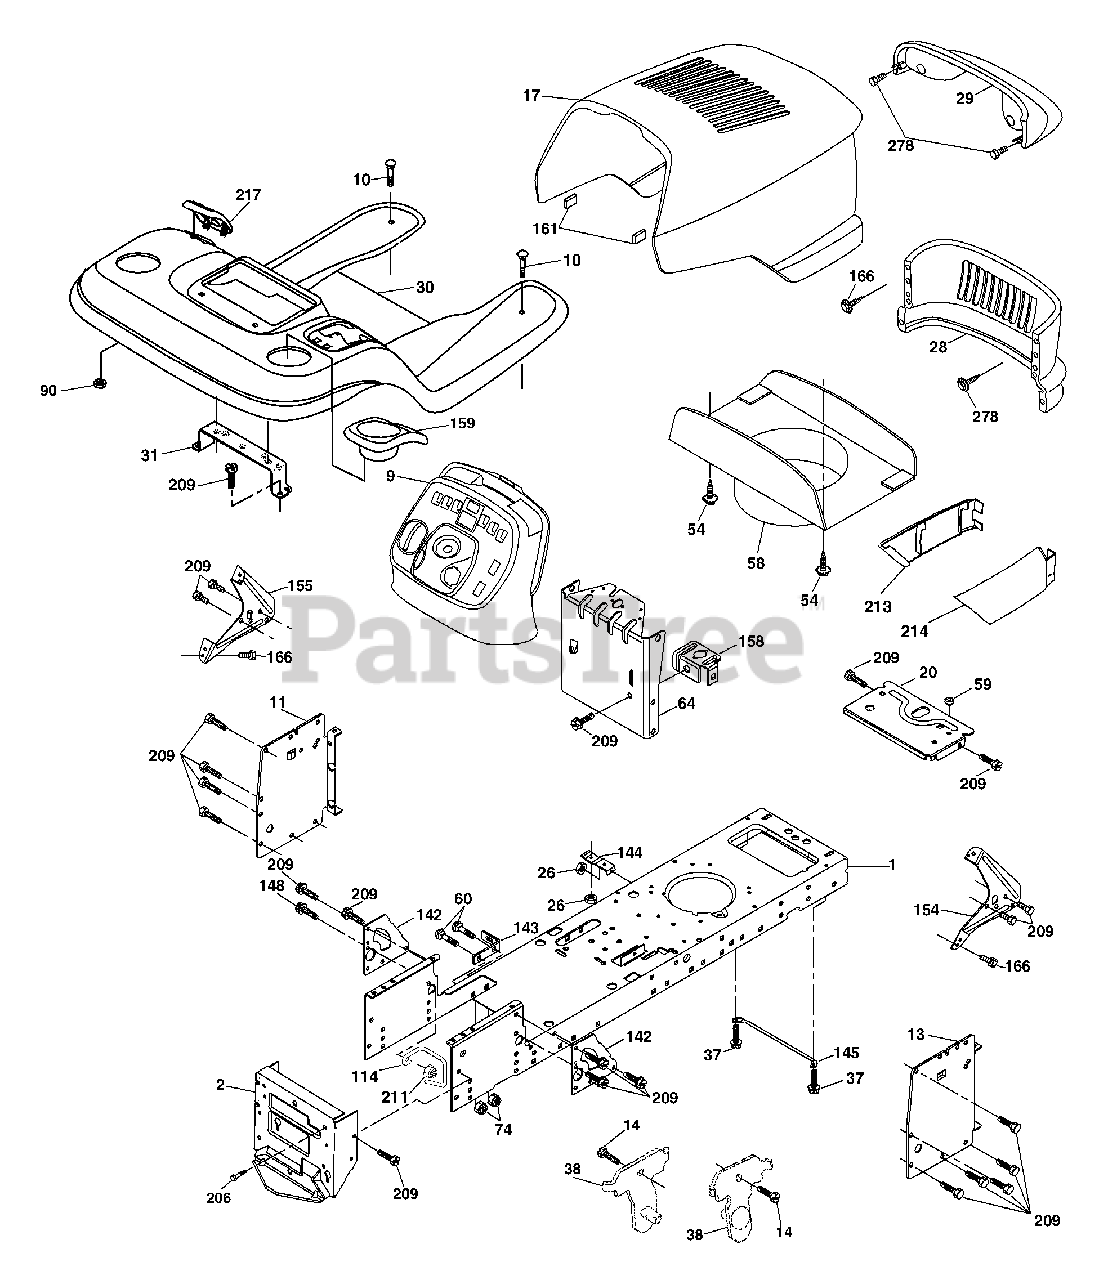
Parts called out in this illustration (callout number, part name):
1	Chassis
2	Drawbar
9	Dash
10	Bolt RDHD SQNK 3/8-16 x 1
11	Panel, Dash, LH
13	Panel, Dash, RH
14	Screw Thdrol 3/8-16 x 1/2
17	Hood Assembly
20	Plate Battery
26	Locknut, Hex, with Insert 3/8-16 unc
28	Grille
29	Lens Bar
30	Fender/Footrest
31	Bracket, Fender/Support
37	Screw, Thdrol. 5/16-18 x 1/2 TYT
38	Bracket Asm Pivot Mower Rear
54	Screw 8-18 x 7/8
58	Duct Hood
59	Bushing
60	Bolt Rdhd Sqnk 3/8-16 unc x 3/4
64	Dash Lower
74	Nut Crownlock 3/8-16 unc
90	Nut Self Thrd Wshd 1/4 Zinc
114	Keeper Belt Rear LH
142	Plate Reinforcement
143	Bracket Swaybar Chassis
144	Bracket Footrest
145	Rod Pivot Chassis/Hood
148	Screw 3/8-16 x 1-1/4
154	Bracket Dash Rh
155	Bracket Dash Lh
158	Parking Brake Bkrt
159	Cupholder
161	Bumper
206	Bolt Shoulder 5/16-18
209	Screw Hexwsh Thdr 3/8-16 x 3/4
211	Nut Hexflange Lock
213	Skirt Grille LH
214	Skirt Grille RH
217	Console Fuel Window
278	Screw 10 x 3/4 Single Lead-Hex
